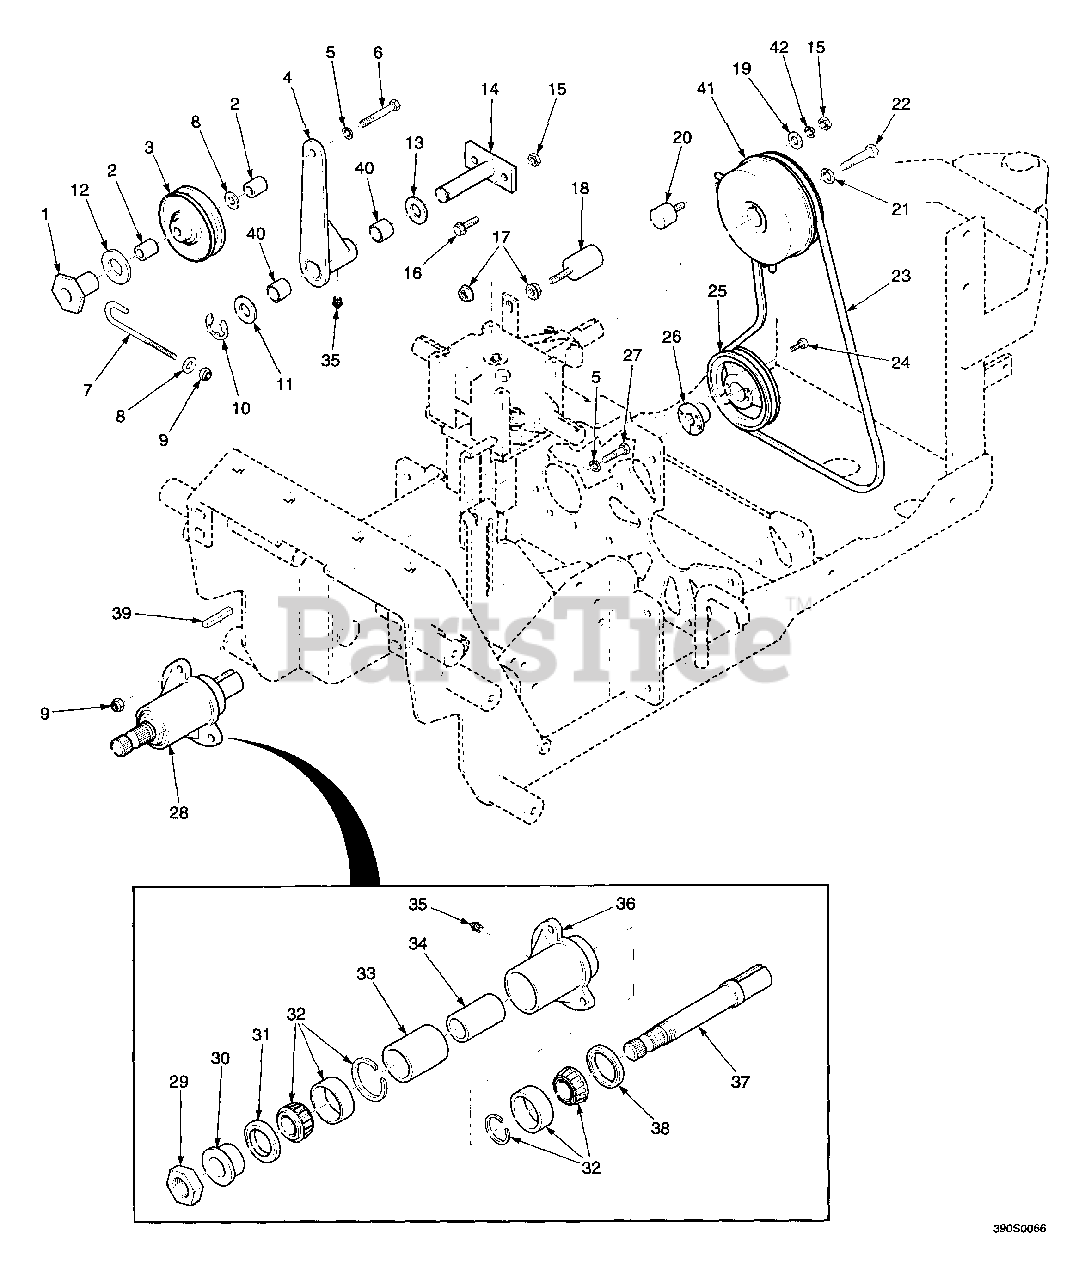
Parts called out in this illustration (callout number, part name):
1	Nut, Special
2	Spacer J-Pull Rod
3	Pulley, Idler
4	Idler Arm, Auxiliary Drive
5	Lockwasher, 3/8"
6	Bolt, Hex Head, 3/8-16 x 3-1/4"
7	J-Pull Rod
8	Flatwasher, 3/8 (.391 x .938 x .105)
9	Hex Locknut, Elastic Stop, 3/8-16
10	Retaining Ring, .75 "E"
11	Flatwasher, 3/4 (.766 x 1.25 x .060)
12	Washer
13	Flatwasher, 3/4 (.766 x 1.25 x .035)
14	Pivot, Auxiliary Drive Idler
15	Hex Nut, 5/16-18
16	Serr. Fl. Hex Head CPSCR, 5/16-18 x 1.00
17	Serr. Fl. Hex Nut, 7/16-14
18	Base, Clutch Anti-Rotation
19	Flatwasher, 5/16"
20	Isolator, Rubber
21	Lockwasher, 7/16"
22	Bolt, Hex Head, 7/16-20 x 2-1/4"
23	Belt, Blower Drive
24	Socket Head Capscrew, 1/4-20 x 1-3/8"
25	Pulley, 5.35 OD
26	Hub, Tapered
27	Bolt, Hex Head, 3/8-16 x 1-1/2"
28	Spindle Assembly, Drive Shaft
29	Nut, 1.06-18
30	Spindle Bushing, Bottom
31	Seal, 2.00 OD x 1.625 Bore
32	Roller Bearing Assembly
33	Spacer, Outside
34	Spacer, Inside
35	Grease Fitting
36	Spindle Housing
37	Shaft, PTO Deck Drive
38	Seal, 2.00 OD x 1.50 Bore
39	Key, 1/4 x 1/4 x 1-1/4"
40	Bushing, Oilite, .753 ID
41	Electric Clutch
42	Lockwasher, 5/16"
